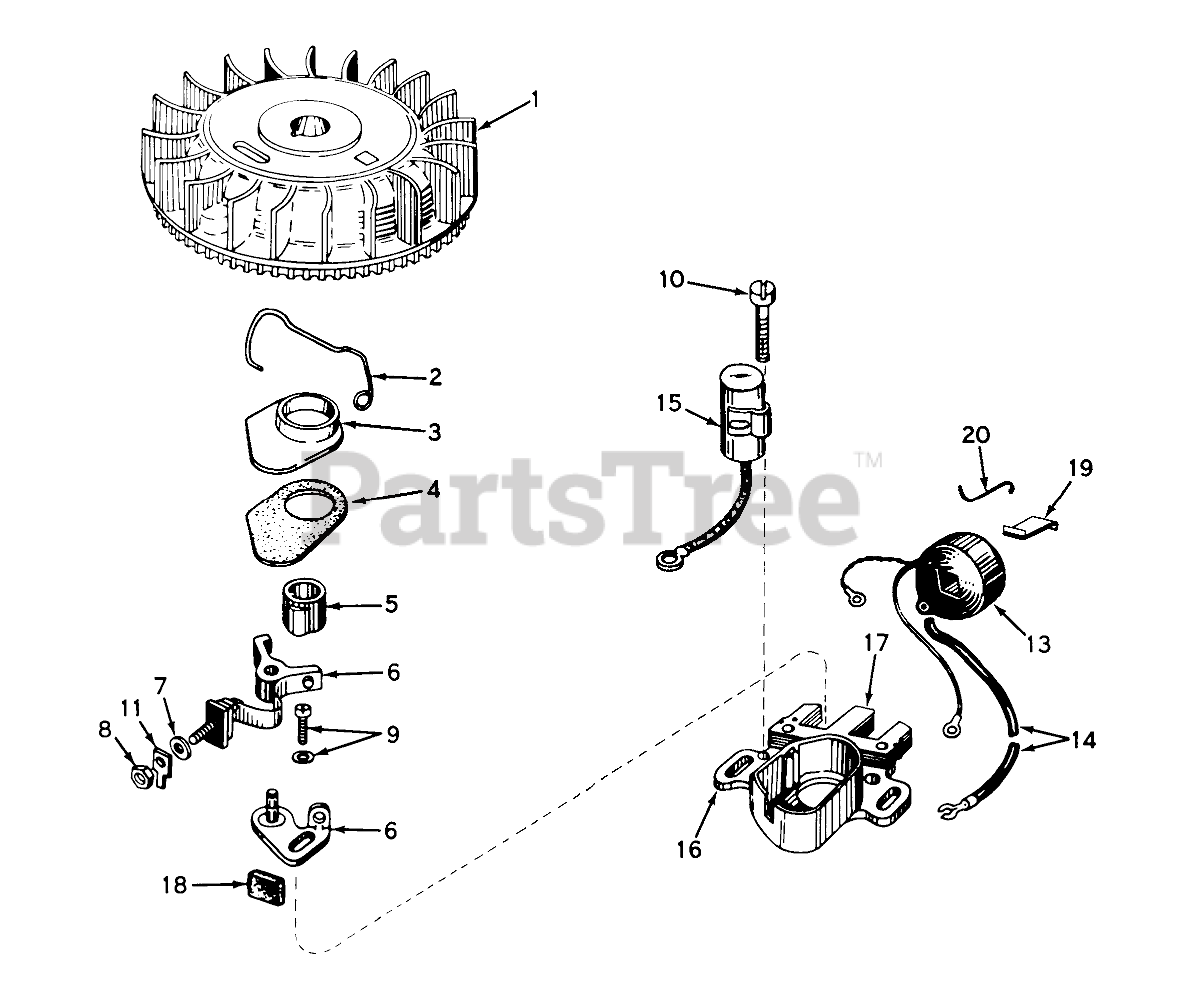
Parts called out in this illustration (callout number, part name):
1	FIywheel
2	Spring Breaker Box
3	Cover, Dust
4	Gasket Dust Cover
5	Cam, Breaker
6	Breaker Assy.
9	Breaker Screw
10	Condenser Screw
11	Terminal
13	Coil Assy. (Incl. Ref. Nos. 14, 15 & 19)
14	Wire, Lead
15	Condenser
16	Core & Plate
17	Starter Assy. (Incl. Nos. 2, 3, 5 thru 14 & 16 thru 19)
18	Felt,Cam Wiper
19	Spring Coil Wedge
20	Clip, Coil
